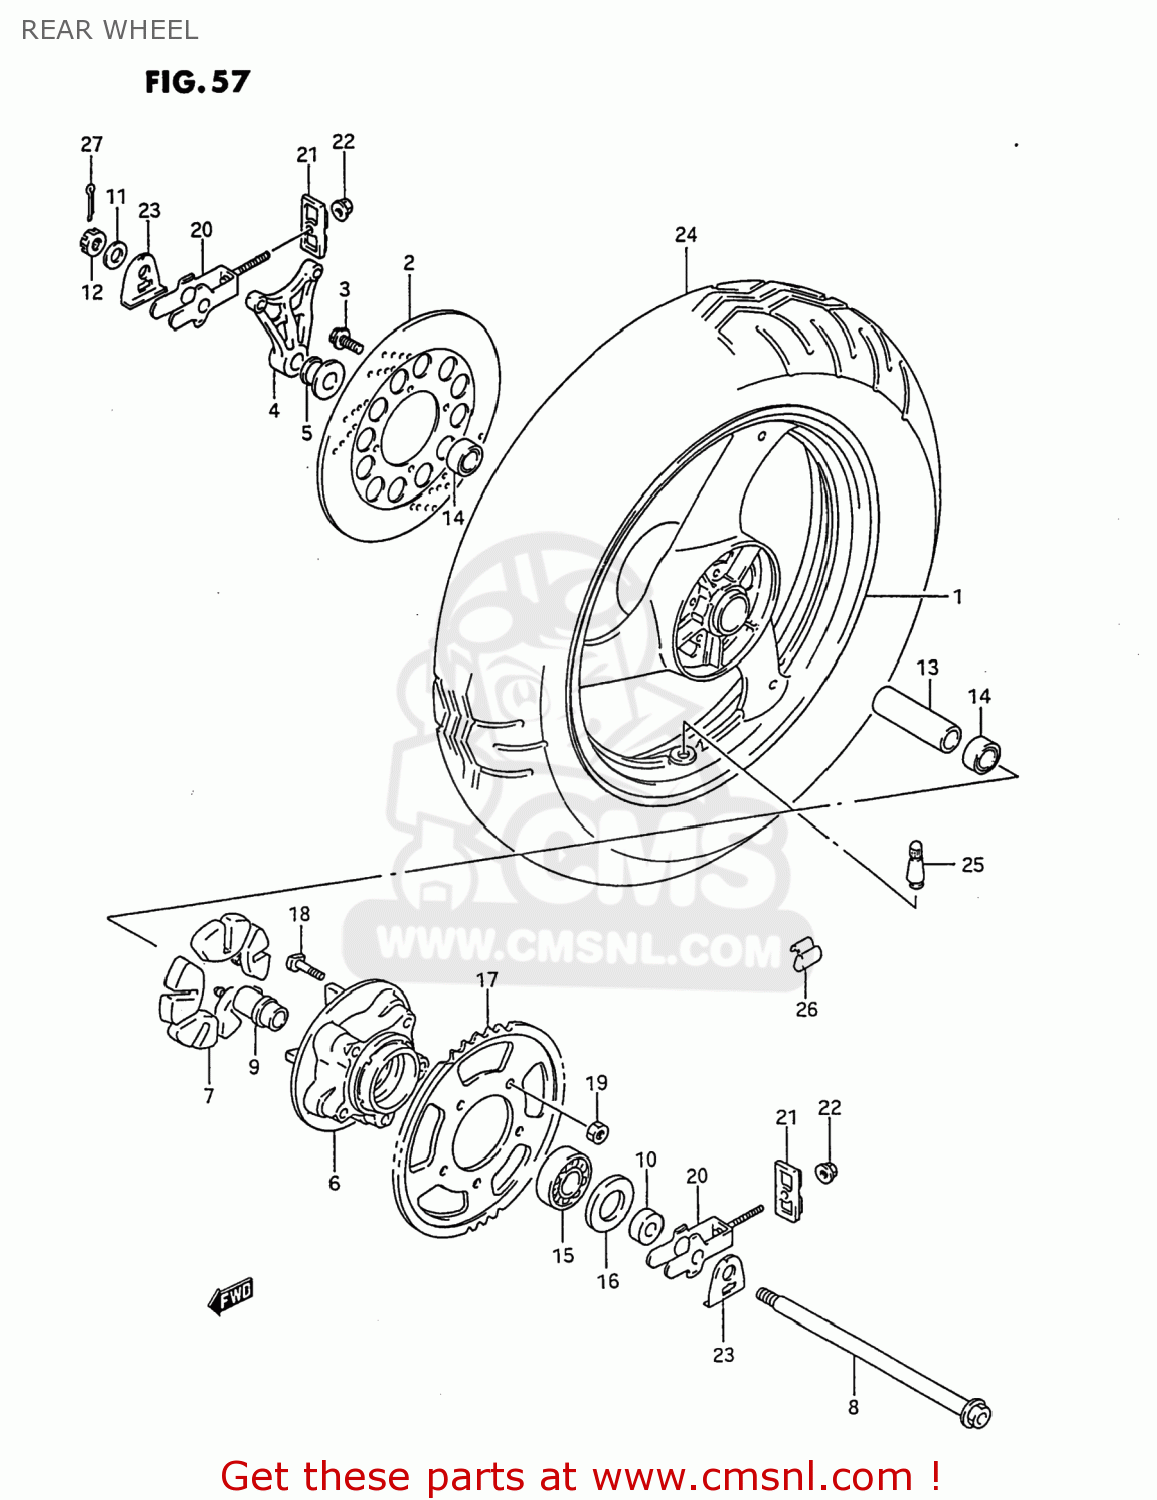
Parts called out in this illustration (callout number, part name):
1	WHEEL,REAR (MT3.50X17)
2	DISC,RR BRAKE
3	BOLT(8X30)
4	BRACKET,RR,CALIPER
5	SPACER,RR AXLE,R
6	DRUM,RR SPROCKET MOUNTING
7	ABSORBER,RR HUB SHOCK
8	AXLE,REAR
9	RETAINER,RR SPROCKET DRUM
10	SPACER,RR AXLE,L
11	WASHER (17X30X3.2)
12	NUT
13	SPACER(17.5X25X88)
14	BEARING
15	BEARING(25X62X17)
16	SEAL,OIL(35X62X8)
17	SPROCKET,RR(NT:47-530)
18	BOLT
19	NUT
20	ADJUSTER,CHAIN
21	PLATE,CHAIN ADJUSTER GUIDE
22	NUT
23	WASHER,CHAIN ADJUSTER
24	TIRE 150/70VB17 (69V) V2
25	VALVE ASSEMBLY,WHEEL,TR412
26	BALANCER,WHEEL (10G)
27	PIN,COTTER
